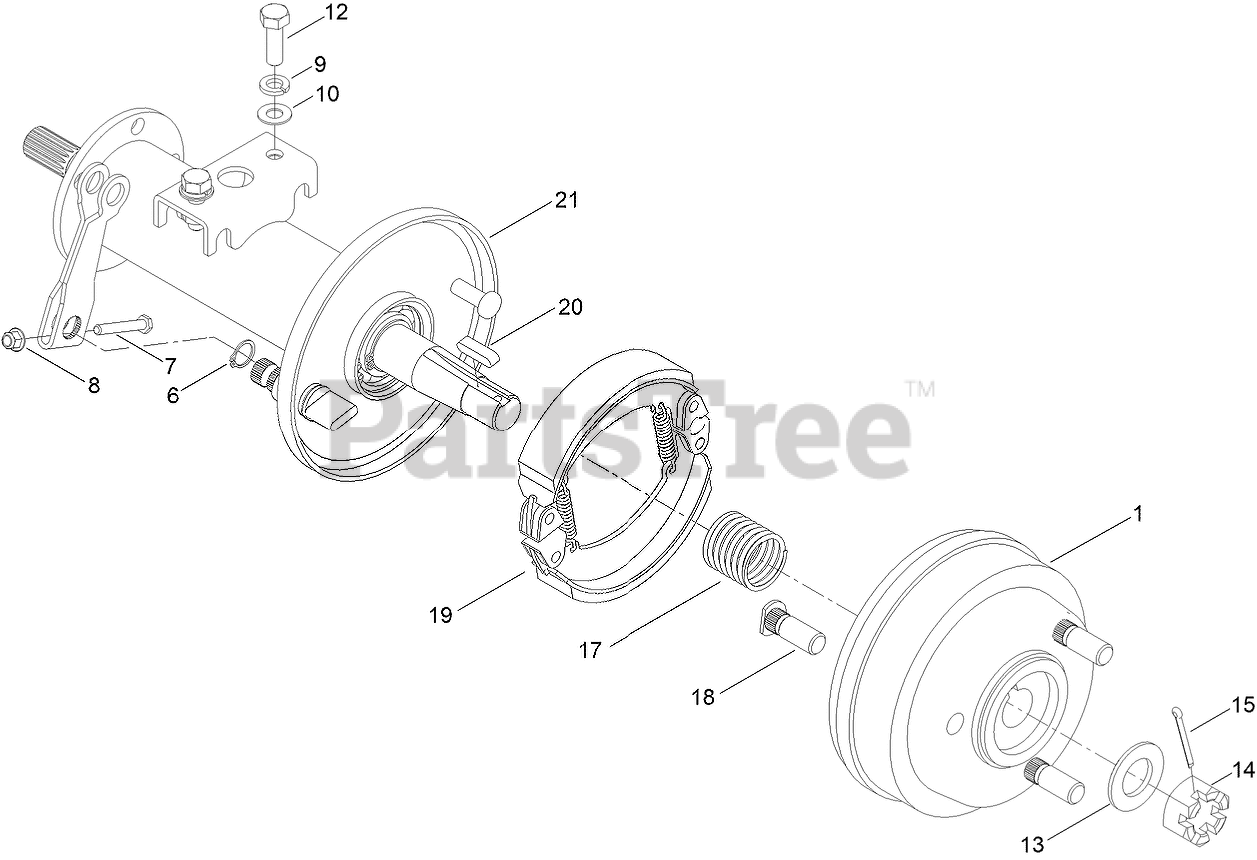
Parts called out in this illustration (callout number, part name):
1	REAR WHEEL MOUNTING PLATE ASM
6	CLIP, CONNECTION BRAKE
8	NUT-FLANGE, NI
9	SPRING WASHER
10	WASHER-PLAIN
12	SCREW-HH
13	WASHER, REAR WHEEL
14	CENTRE NUT, REAR WHEEL
15	PIN, WHEEL NUT
17	SPRING, REAR AXLE
18	BOLT, REAR AXLE
19	BRAKE PAD, REAR AXLE
20	KEY, REAR AXLE
21	PARTS, REAR AXLE
